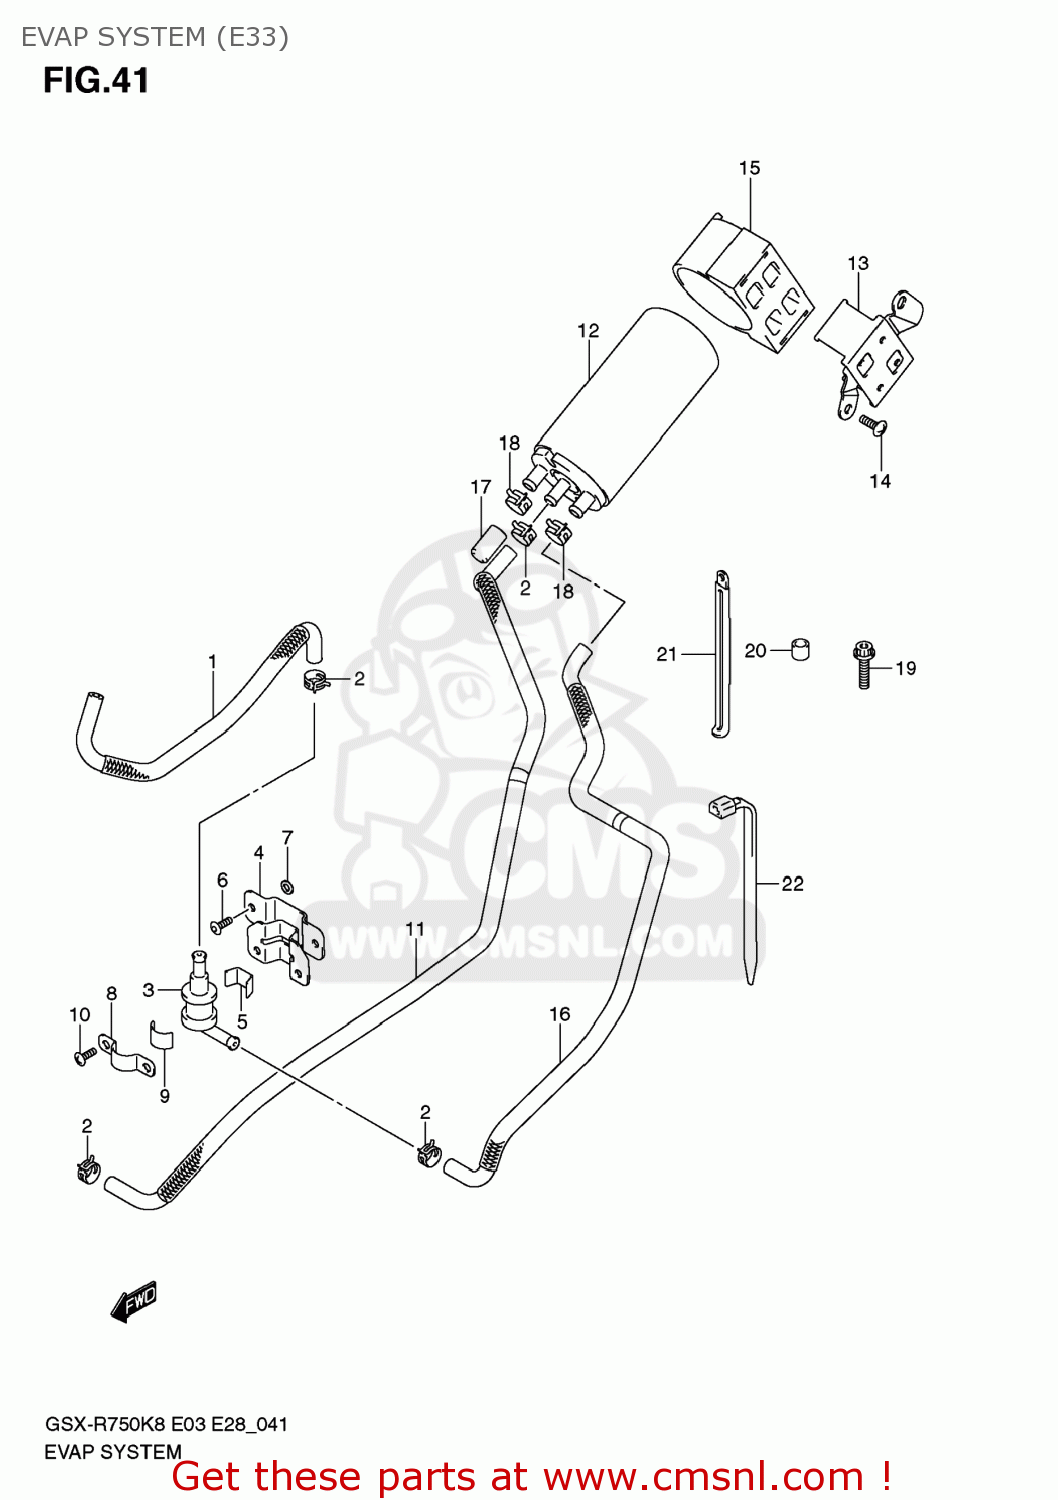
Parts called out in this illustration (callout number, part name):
1	HOSE,TANK & BREATHER VALVE
2	CLIP
3	VALVE,FUEL TANK BREATHER
4	PLATE,BREATHER VALVE
5	CUSHION
6	RIVET
7	WASHER
8	PLATE,FUEL TANK BREATHER NO.2
9	CUSHION
10	SCREW
11	HOSE,CSTR & BREATHER VALVE
12	CANISTER ASSY,CHARCOAL
13	BRACKET,CANISTER
14	SCREW(6X16)
15	CUSHION,CANISTER
16	HOSE,CSTR PURGE
17	CAP,OD:11.5
18	CLIP
19	BOLT
20	SPACER(6.5X10X9.4)
21	CLAMP(L:135)
22	CLAMP(L:165)
